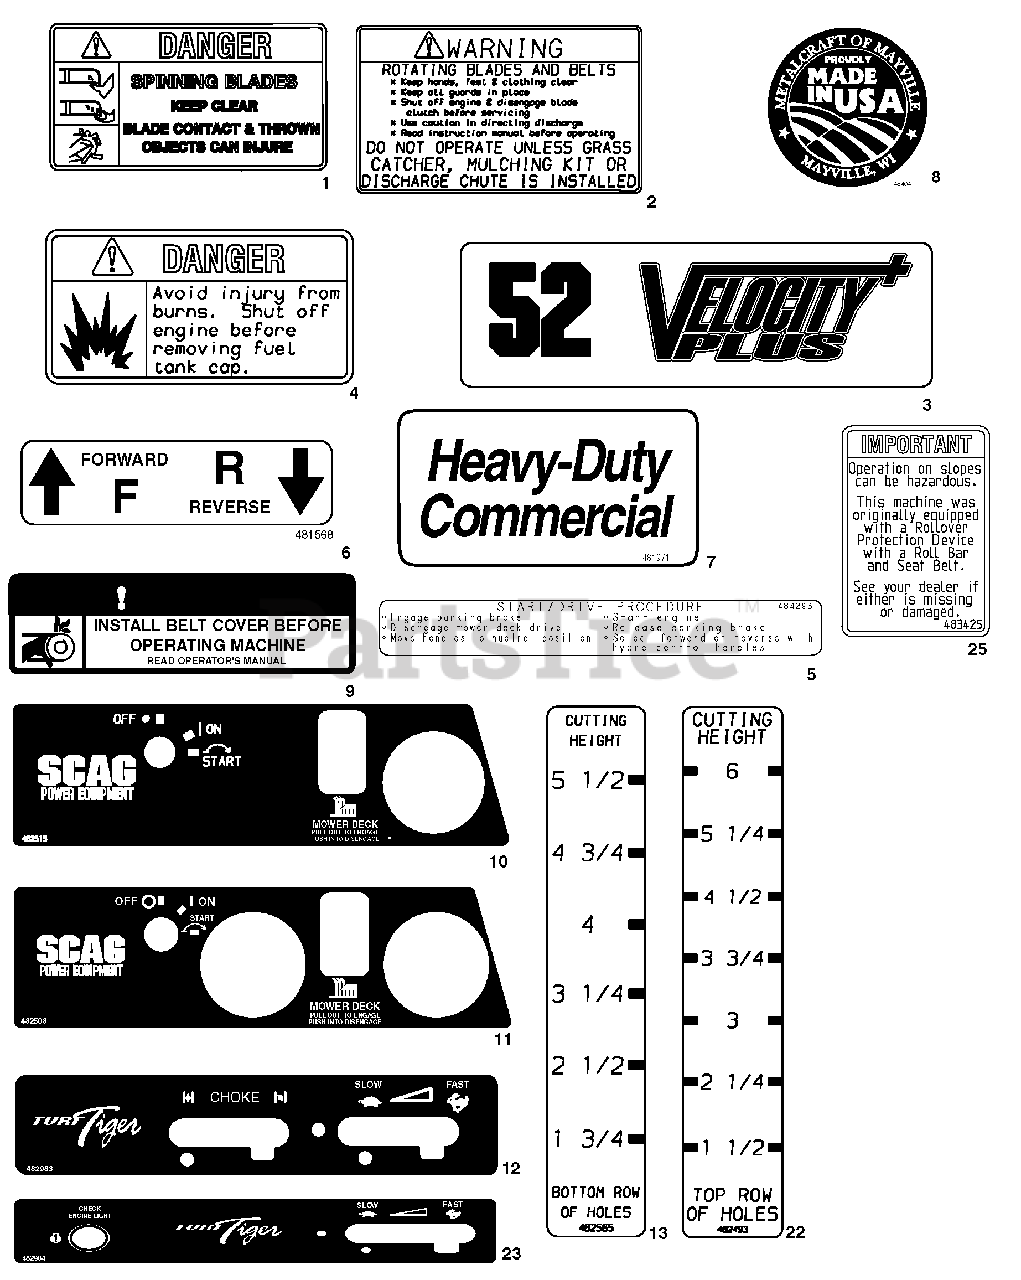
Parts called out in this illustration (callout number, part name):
1	Decal, Danger - Spinning Blades
2	Decal, Warning - Rotating Blades
3	Decal, 52 Velocity Plus
3	Decal, 61 Velocity Plus
3	Decal, 72 Advantage
3	Decal, 72 Velocity Plus
4	Decal, Fuel Tank
5	Decal, Start / Drive
6	Decal, Traction Control
7	Decal, Heavy-Duty Commercial
8	Decal, Metalcraft-Made In USA
9	Decal, Belt Cover
10	Decal, Instrument Panel - Upper (Air-Cooled)
11	Decal, Instrument Panel - Upper (Kawasaki)
12	Decal, Instrument Panel-Lower
13	Decal, Cutting Height - Lower
22	Decal, Cutting Height - Upper
23	Decal, Instrument Panel - Lower (DFI & EFI only)
25	Decal, ROPS
